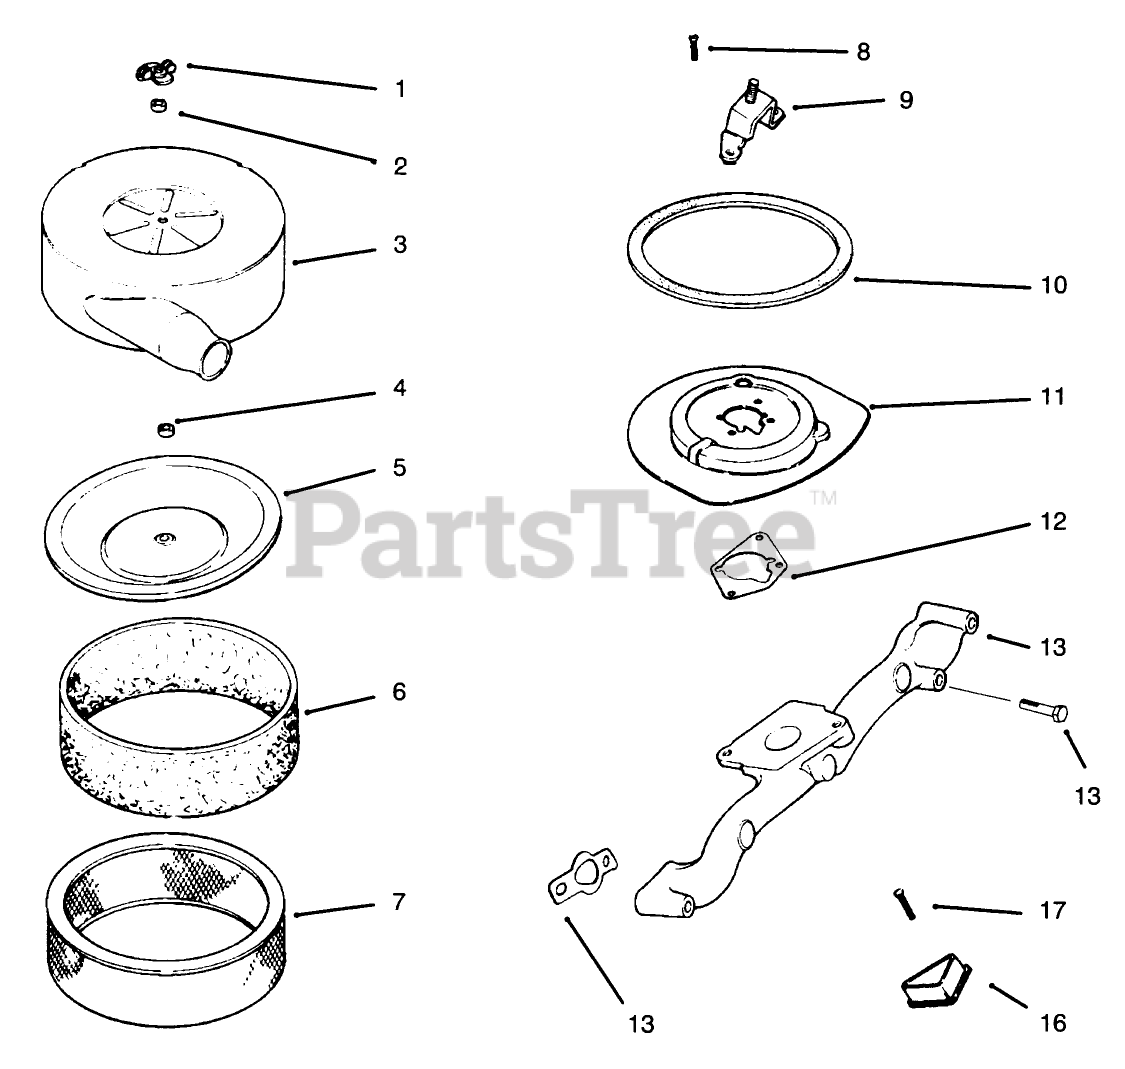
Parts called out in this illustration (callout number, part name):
1	Wingnut
2	Seal
3	Cover-Air Cleaner
4	Seal
5	Cover-Inner AirCleaner
6	Bement-Precleaner
7	Bement-Air Cleaner
8	Screw
9	Bracket-Air Cleaner
10	Seal-Air Cleaner
11	Base-Air Cleaner
12	Gasket
13	Gasket-Intake, Manifold
14	Screw
15	Manifold
16	Plug
17	Screw
